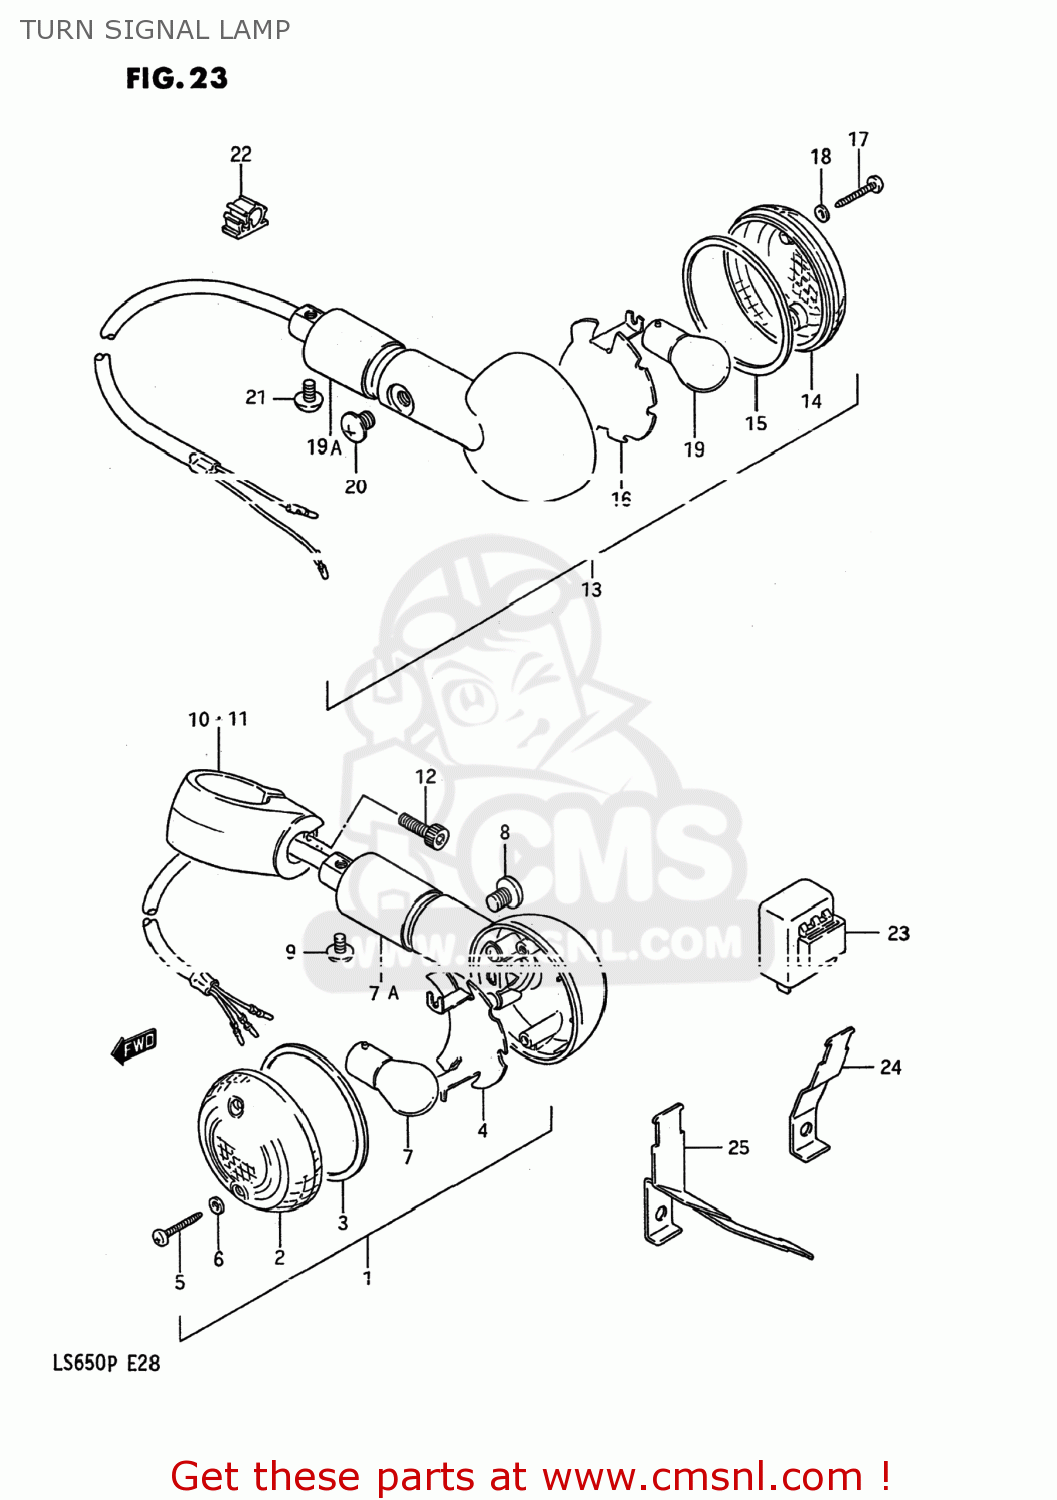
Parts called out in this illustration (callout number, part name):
1	LAMP ASSEMBLY,FRONT TURN SIGNAL
2	LENS
3	GASKET (NAS)
4	REFLECTOR
5	SCREW ,4X25
6	GASKET (NAS)
7	BULB(12V23/8W,TOKAI DENSO)
7A	STAY,TURNSIGNAL LAMP
8	SCREW
9	SCREW
10	BRACKET,FR TURNSIGNAL LAMP,R
11	BRACKET,FR TURNSIGNAL LAMP,L
12	BOLT
13	LAMP ASSEMBLY,REAR TURN SIGNAL
14	LENS
15	GASKET (NAS)
16	REFLECTOR
17	SCREW ,4X25
18	GASKET (NAS)
19	BULB 12V 21W
19A	STAY,TURNSIGNAL LAMP
20	SCREW
21	SCREW
22	CLAMP
23	RELAY ASSEMBLY,TURN SIGNAL
24	BRACKET,TURN SIGNAL RELAY
25	BRACKET,TURNSIGNAL RELAY
